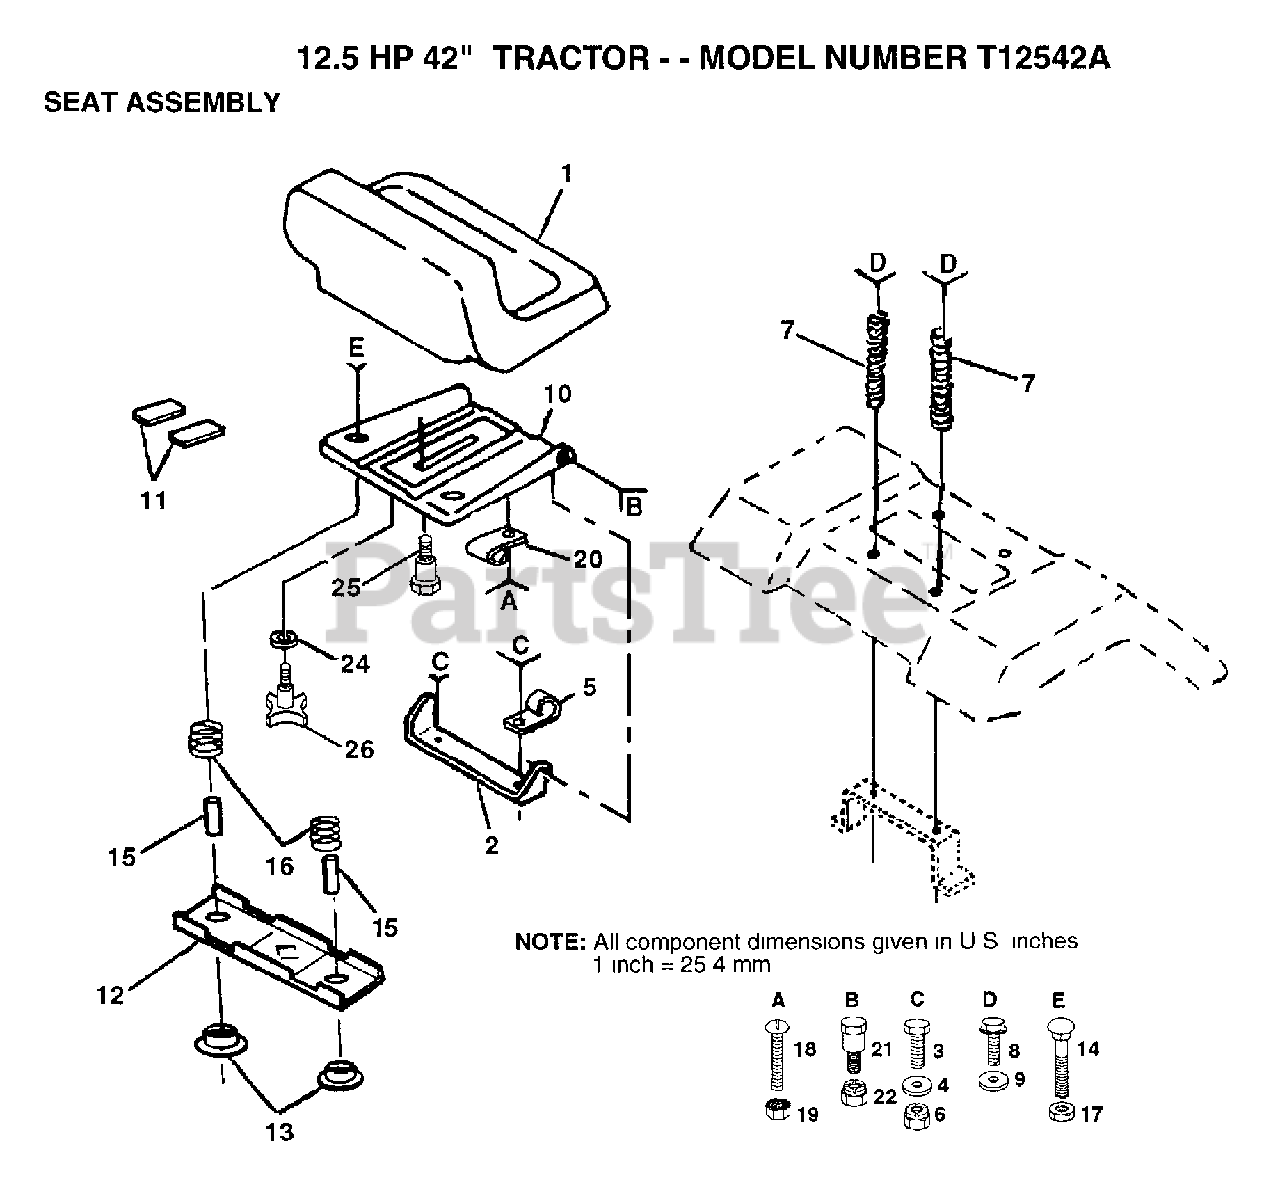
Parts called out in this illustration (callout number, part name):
4	WASHER PM
5	CLIP T
7	SPRING COMPRESSIO
8	SCREW GTV
9	WASHER
11	STRIP FORM
12	BRKT SWITCH
13	BUSHING
15	SPACER SPLIT
16	SPRING COMPRESSED
19	"NUT,KEPS"
24	WASHER
25	"BOLT,SHOULDER"
26	"KNOB 1/2"" YT"
